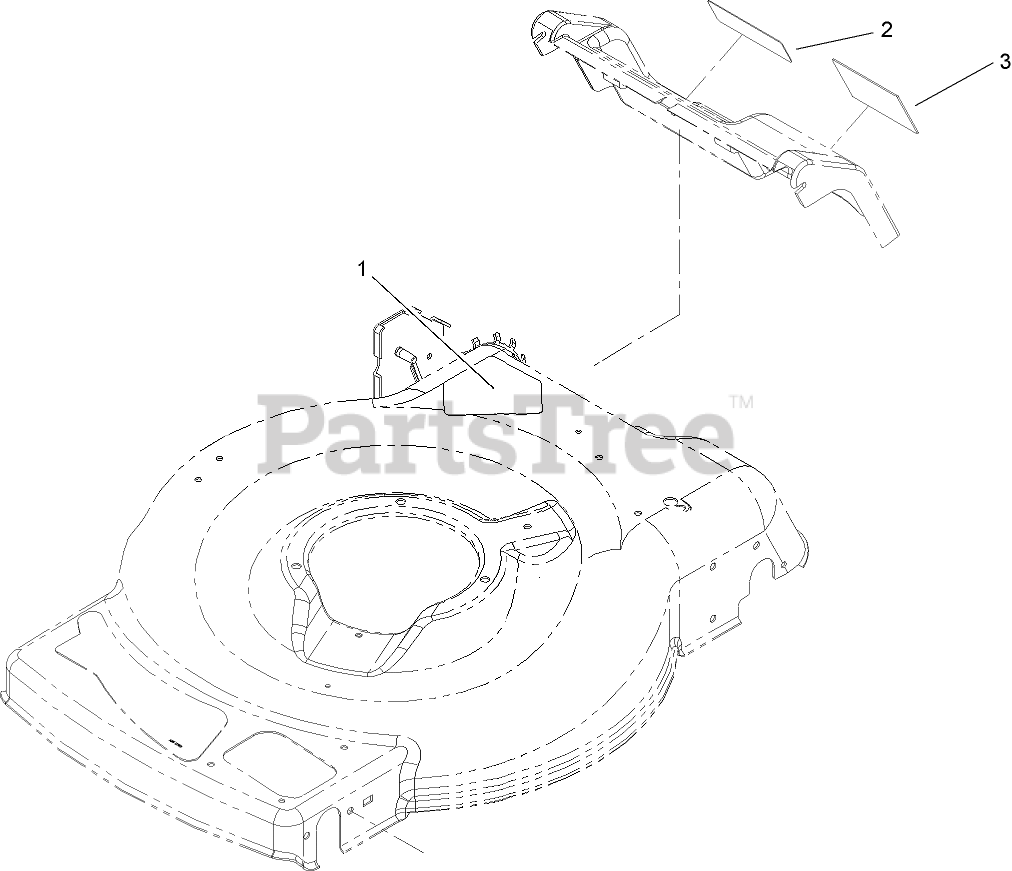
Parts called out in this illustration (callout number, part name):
1	DECAL-DANGER
2	DECAL-WARNING
3	DECAL-WARNING
